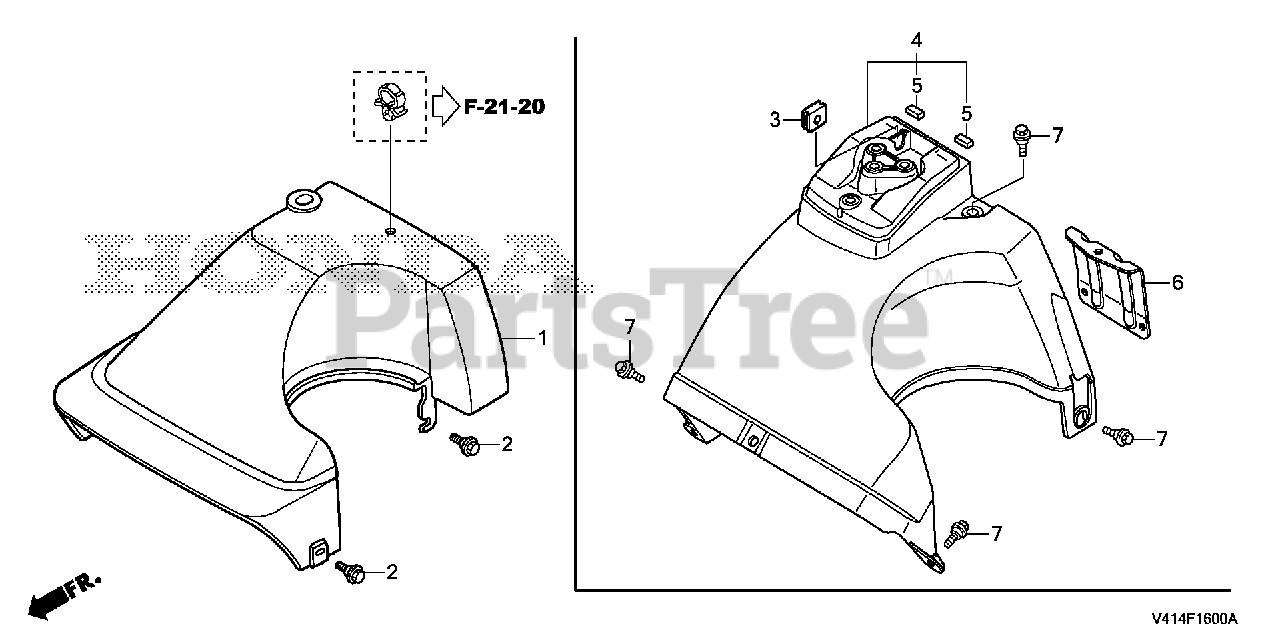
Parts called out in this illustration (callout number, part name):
3	GROMMET, WIRE
4	COVER, MOTOR *R280* (POWER RED)
5	RUBBER, COVER MOUNT
6	BRACKET B, MOTOR COVER
7	BOLT, FLANGE (6MM)
